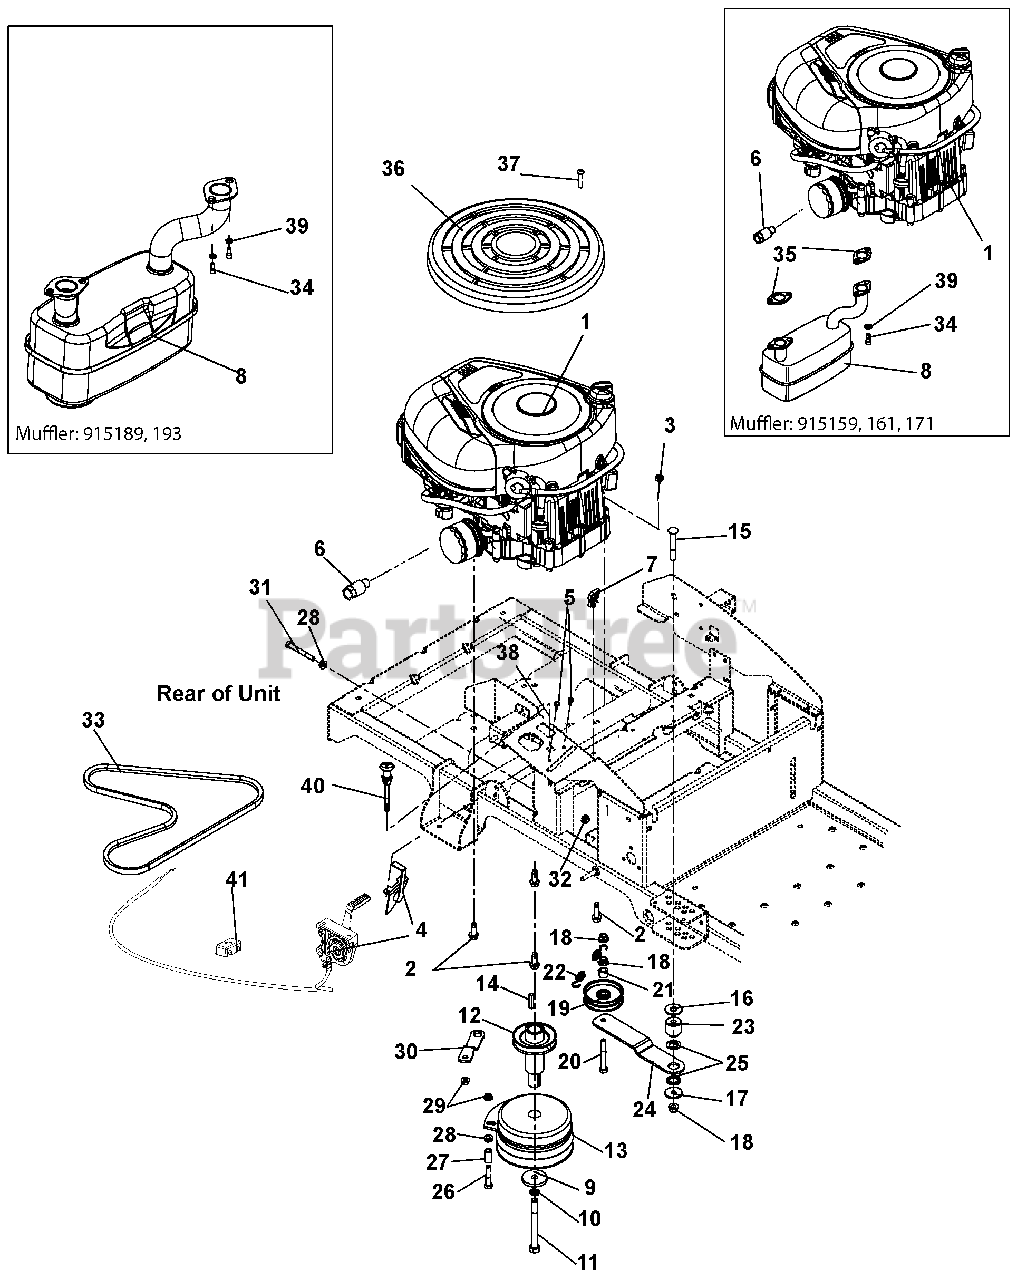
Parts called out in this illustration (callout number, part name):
1	ENGINE, KOHLER TWIN 20 HP
1	ENGINE, KOHLER TWIN - 22HP
1	ENGINE, B&S 16 HP TWIN
2	@SCR-TAP .38-16X1.25 HWH TR YZ
3	@NUT-LK-CTR-JAM .375-16 YWZC
4	CABLE, THROTTLE
4	CABLE, THROTTLE/CHOKE
5	@SCR-TAP 10-24X.50 HWH TR YWZC
6	DRAIN, OIL
7	WIRE CLIP
8	MUFFLER, KOHLER TWIN
8	MUFFLER - TWIN BRIGGS
9	WSHR-FL-STL .469X2.00X.25 YWZC
10	@WSHR-LK .44X.109 REG YWZC
11	BLT-HEX .44-20X4.50 GR8 YWZC
12	WMT-PTO EXTENSION W/SHEAVE
13	CLUTCH, 105 FT*LB MONO POLE
14	KEY-SQ .25 X 1.25 X .25 SAE
15	@BLT-RDHDSQNK .38-16X2.75 G5YZ
16	@WSHR-FL-STL.563X1.38X.109YWZC
17	WSHR-FL-STL .406X1.375X.135 YZ
18	@NUT-LK-NYL-FLG .38-16 YWZC
19	PULLEY, ENGINE CLUTCH 03608
20	@BLT-HEX .38-16X2.75 GR5 YWZC
21	BSHG-SLV .391X.688X.52 PM
22	SPRING, EXTENSION
23	SPACER, GROUND DRIVE IDLER
24	IDLER ARM, GROUND DRIVE
25	BUSHING, IDLER ARM
26	SCR-CAP .31-18X1 3/4 S/HD YWZC
27	SPACER, RUBBER 5/16 IDX1.0 LG
28	@NUT-SPNLK-FLG .312-18 YWZC
29	@NUT-LK-TOP-FLG .31-18 YWZC
30	BRKT, CLUTCH STOP
31	@BLT-HEX .31-18X2.75 GR5 YWZC
32	@NUT-LK-NYL-FLG .31-18 YWZC
33	V-BELT, HA-RAW EDGE
34	SCR-CAP .31-18X.75 S/HD
35	GASKET, MUFFLER COURAGE TWIN
36	GUARD, BRIGGS ENGINE
37	SCREW, 8-16X.87 PHPAN 3 LOBE
38	PLUG, 5/8" SQ BLACK (14-20GA)
39	@WSHR-LK .31X.078 REG YWZC
40	CABLE, CHOKE (SNAP IN)
41	CLIP, ENGINE CABLE
